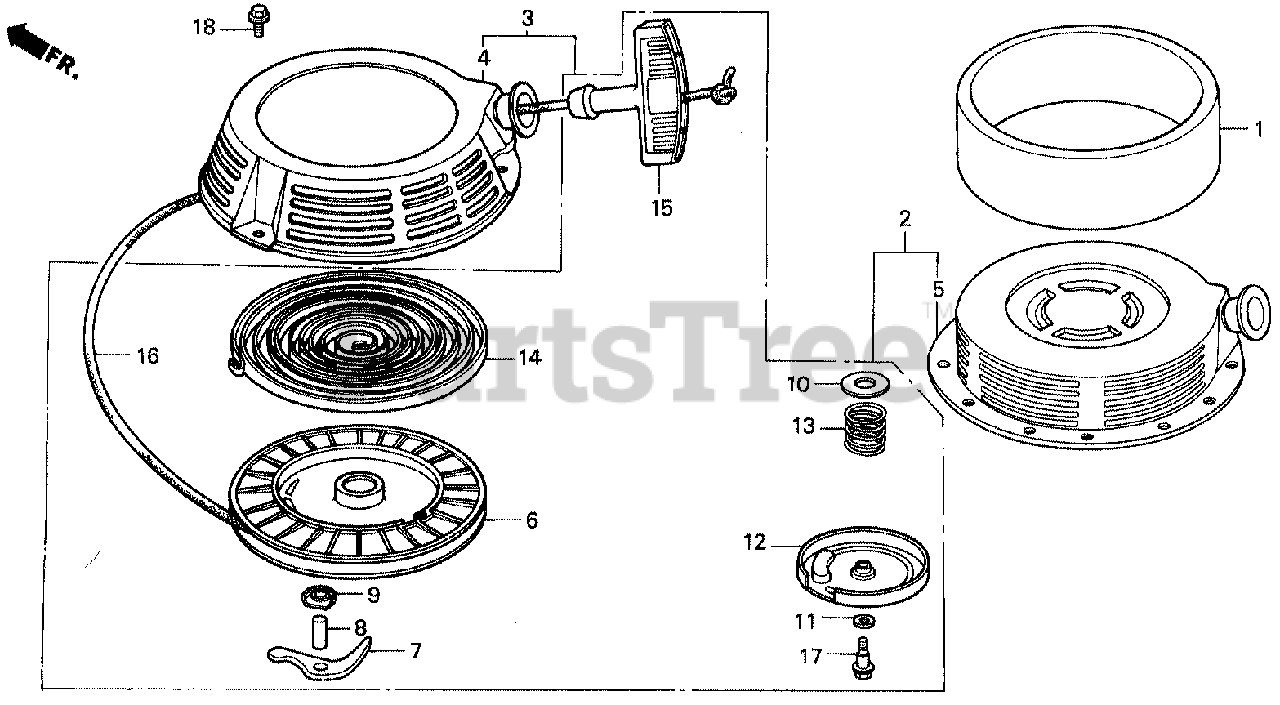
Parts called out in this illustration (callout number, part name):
1	FILTER, AIR
2	STARTER ASSY., RECOIL *R8* (Honda Code 3417292). (BRIGHT RED)
5	CASE, RECOIL STARTER *R8* (Honda Code 3577582). (BRIGHT RED)
6	REEL, STARTER
7	RATCHET, STARTER
8	SHAFT, RATCHET
9	PLATE, GUIDE
10	PLATE A, FRICTION
11	PLATE B, FRICTION
12	COVER, REEL STARTER
13	SPRING, FRICTION
14	SPRING, RETURN
15	GRIP, STARTER
16	ROPE, STARTER (#6X64") (N/A: USE ALT P/N (Honda Code 2106433). 08560-ZG921-11)
17	BOLT, REEL COVER
18	BOLT, FLANGE (6X10)
